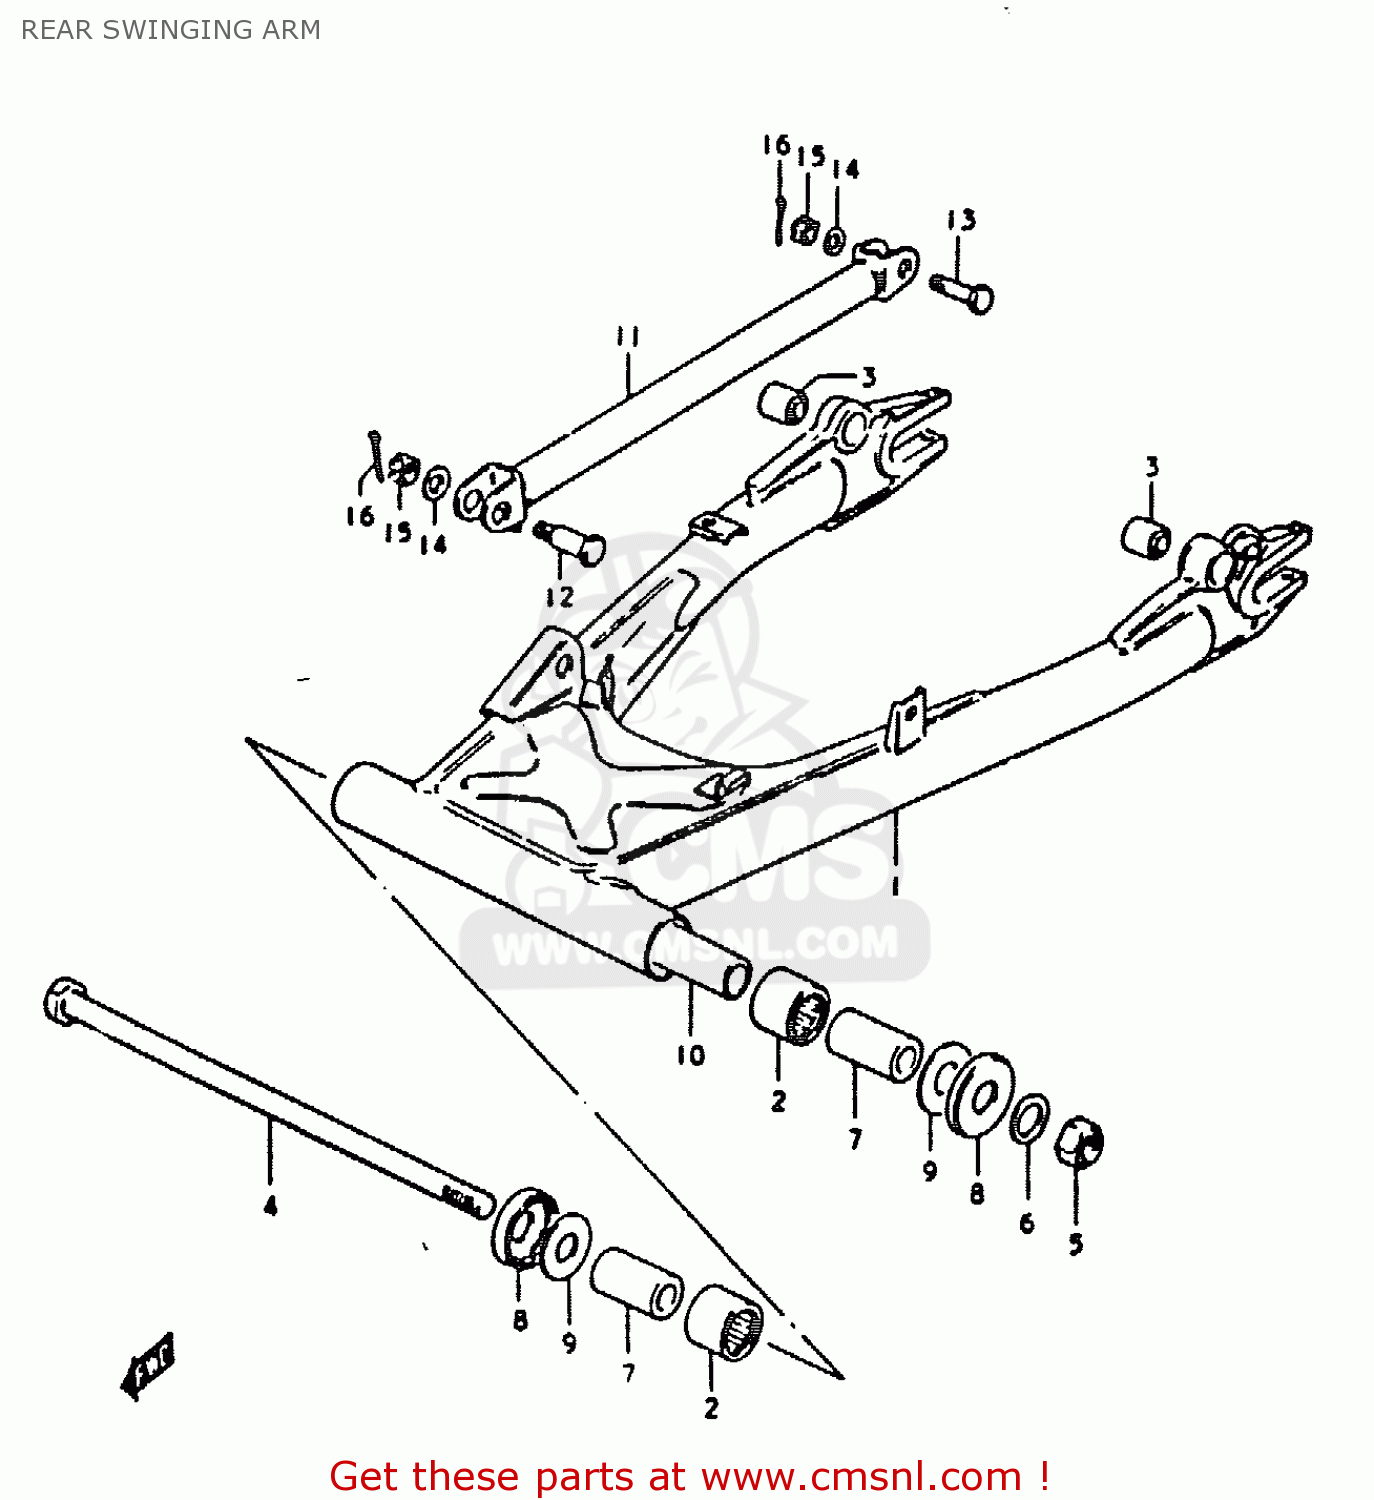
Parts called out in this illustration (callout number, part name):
1	SWING ARM ASSEMBLY,REAR
2	BEARING(25X33X30)
3	BUSH
4	SHAFT,REAR SWING ARM
5	NUT 16MM
6	WASHER
7	SPACER,RR SWGARM PIVOT
8	COVER,RR SWGARM DUST SEAL
9	WASHER
10	SPACER,RR SWGARM PIVOT CTR
11	LINK,REAR TORQUE
12	BOLT
13	BOLT(10X39)
14	WASHER
15	NUT
16	PIN 20X20
